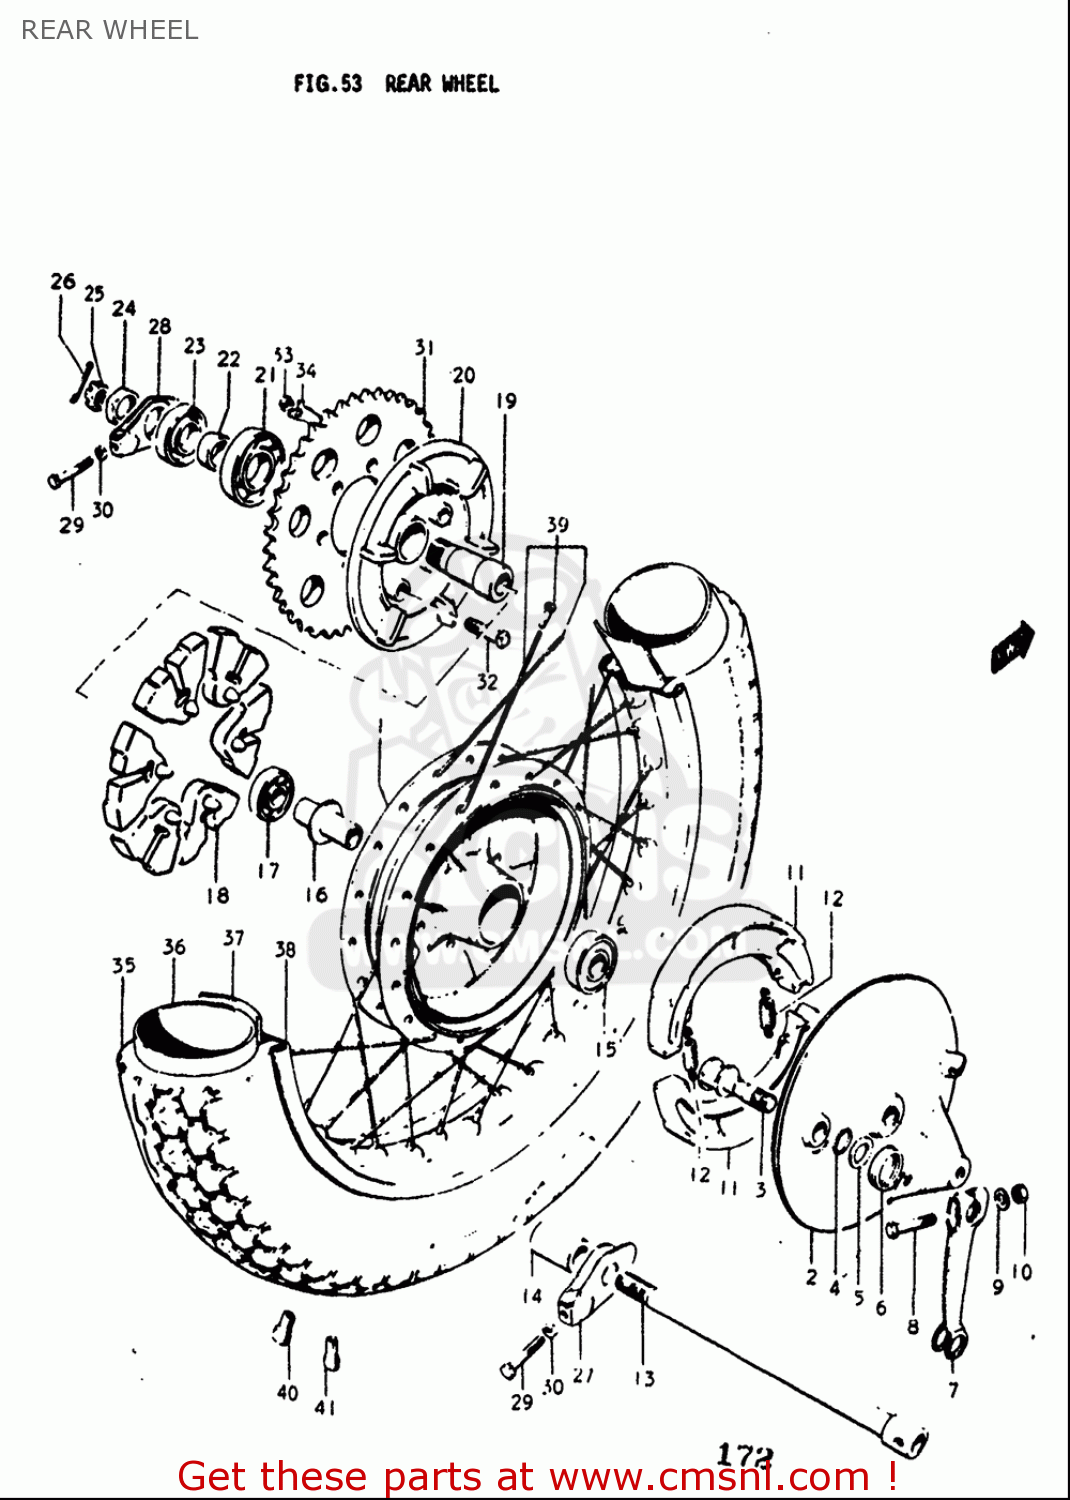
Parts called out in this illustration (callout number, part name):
4	O RING(D:2.4,ID:14.8)
5	WASHER(15.5X24X1.6)
6	SPRING
8	BOLT
9	WASHER
10	NUT
11	SHOE SET,BRAKE (NAS)
12	SPRING,BRAKE SHOE
13	AXLE,REAR
15	BEARING
16	SPACER
17	BEARING
18	ABSORBER,RR HUB SHOCK
21	BEARING(25X52X15)
22	SPACER (25X30.5X11.3)
23	SEAL,OIL(30.5X52X8)
24	NUT
25	NUT 16MM
26	PIN, COTTER
28	ADJUSTER,CHAIN,L
29	BOLT(8X50)
30	NUT
32	BOLT(10X35.5)
33	NUT
34	WASHER
36	TUBE ASSY,INNER
37	PROTECTOR,INNER TUBE
38	RIM,RR WHEEL
39	SPOKE SET,RR WHEEL
40	BALANCER,WHEEL (30G)
41	BALANCER,WHEEL (B)
